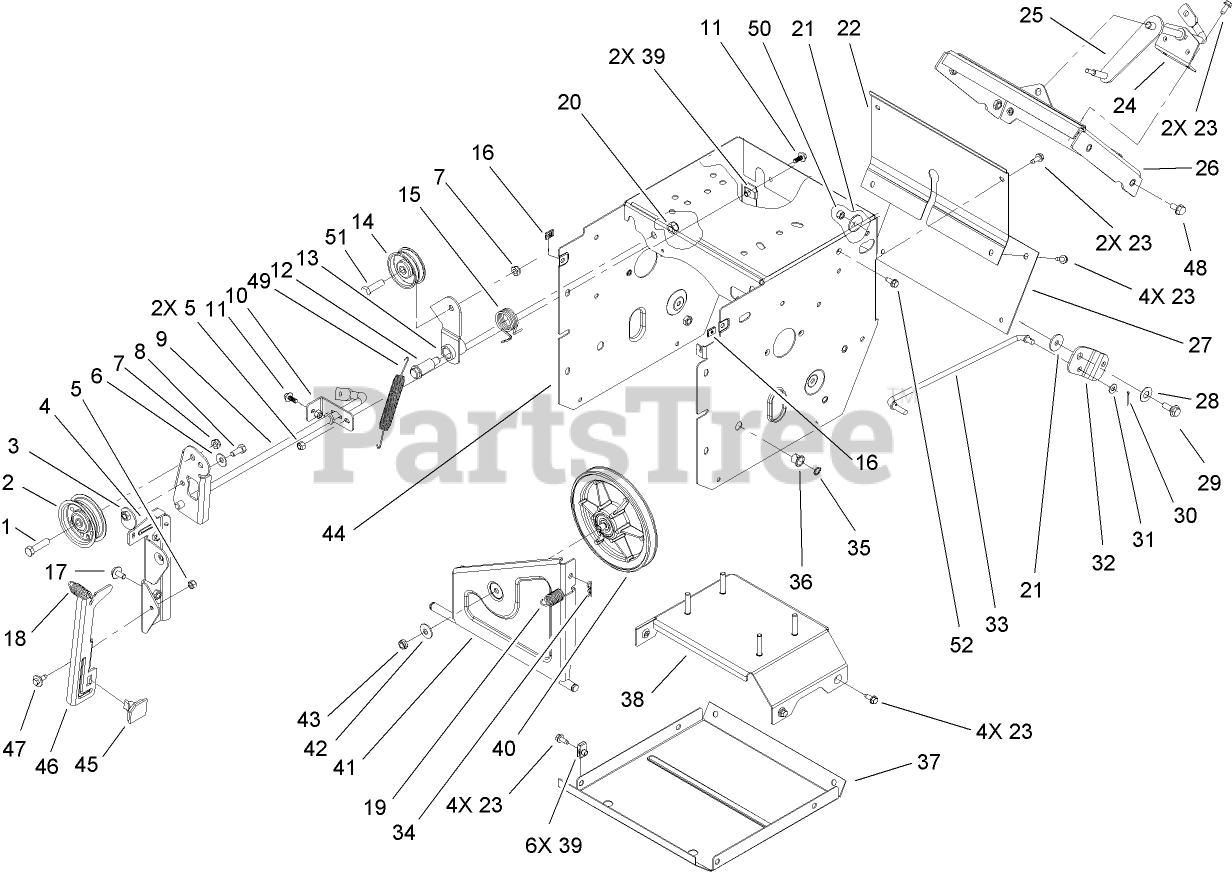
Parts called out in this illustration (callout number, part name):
1	SCREW-HH
2	PULLEY-IDLER
5	NUT-LOCK, NI
6	WASHER-BELLEVILLE
8	SCREW-HH
9	IMPELLER CLUTCH ASM
10	BRACKET-REAR, CLUTCH
11	SCREW-HHF
12	BOLT-SHOULDER
13	ARM-IDLER, TRACTION
14	PULLEY-IDLER
15	SPRING-TORSION
16	NUT-SPEED
17	SCREW-HHF
18	SPRING-EXTENSION
19	SPRING-EXTENSION
20	NUT-LOCK, NI
21	WASHER-PIVOT
22	COVER-UPPER
23	SCREW-HWH
24	BRACKET-ROD, SHIFT
25	LEVER-CONTROL, TRACTION
26	SHIFT PLATE ASM
27	COVER-LOWER
28	WASHER
29	SCREW-SHOULDER
30	PIN-COTTER
31	WASHER-PLAIN
32	BELLCRANK-DRIVE
33	LINK-CONTROL, SPEED
35	RING-RETAINING
36	BUSHING-NYLINER
37	PAN-BOTTOM
38	FRAME BRACE ASM
40	PULLEY-TRACTION
41	BRACKET-WHEEL, FRICTION
42	WASHER-BELLEVILLE
43	NUT-HEX
44	TRACTION FRAME ASM
45	PAD-BRAKE
47	SCREW-SHOULDER
48	SCREW-HWHTF
50	NUT-LOCK, NI
51	SCREW-HH
52	SCREW-HWH
